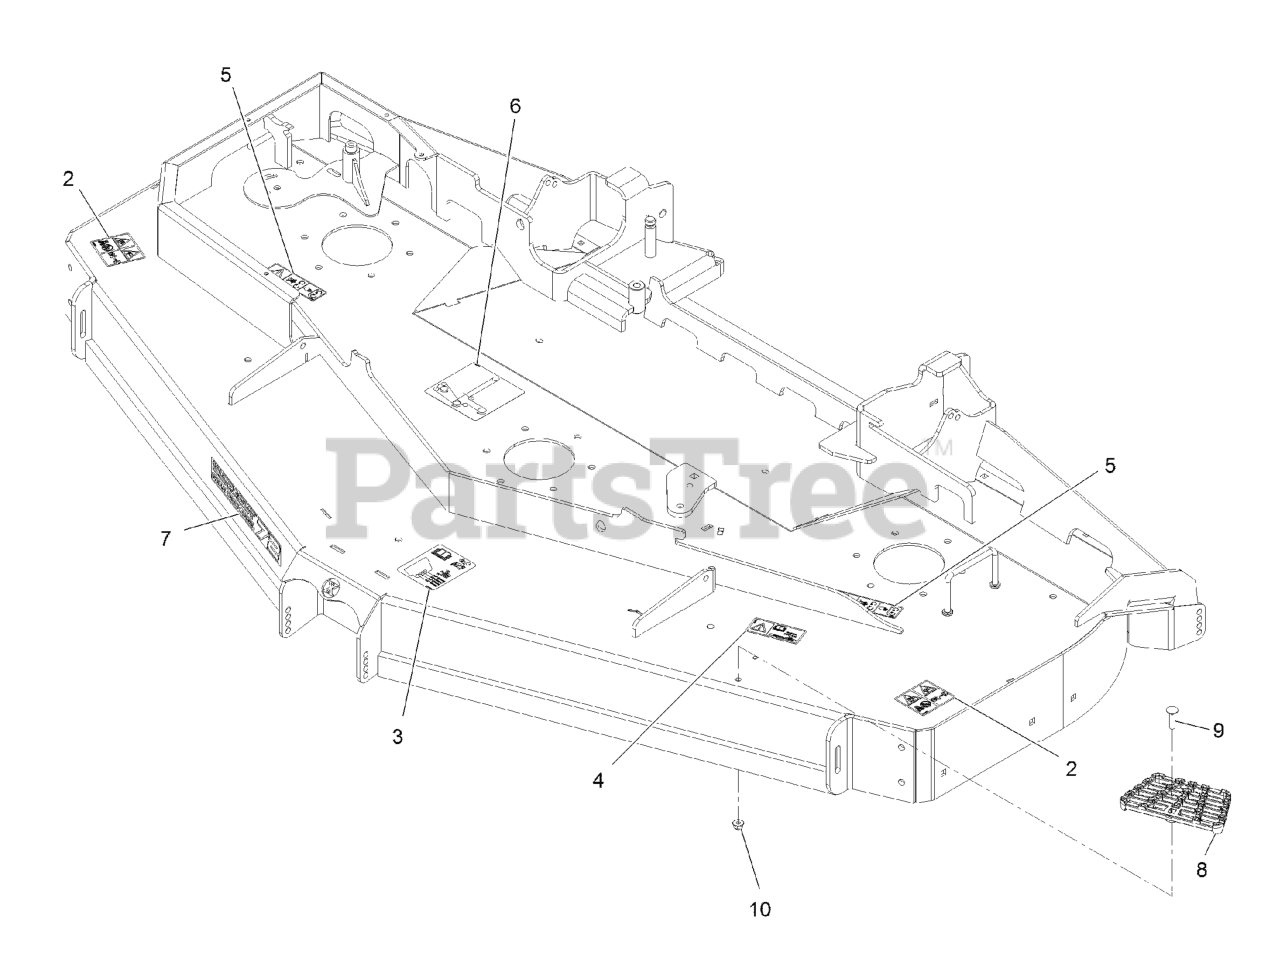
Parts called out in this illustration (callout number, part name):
2	DECAL-DANGER, THROWN OBJECT
3	DECAL-ROLLER, ANTI-SCALP
4	DECAL-TORQUE, BOLT
5	DECAL-COVER, MISSING
6	DECAL-ROUTING, BELT
7	Decal, 72Rd
8	STEP-DECK
9	Bolt-Carriage 5/16-18 X 1 1/4
10	NUT-HF, NI
